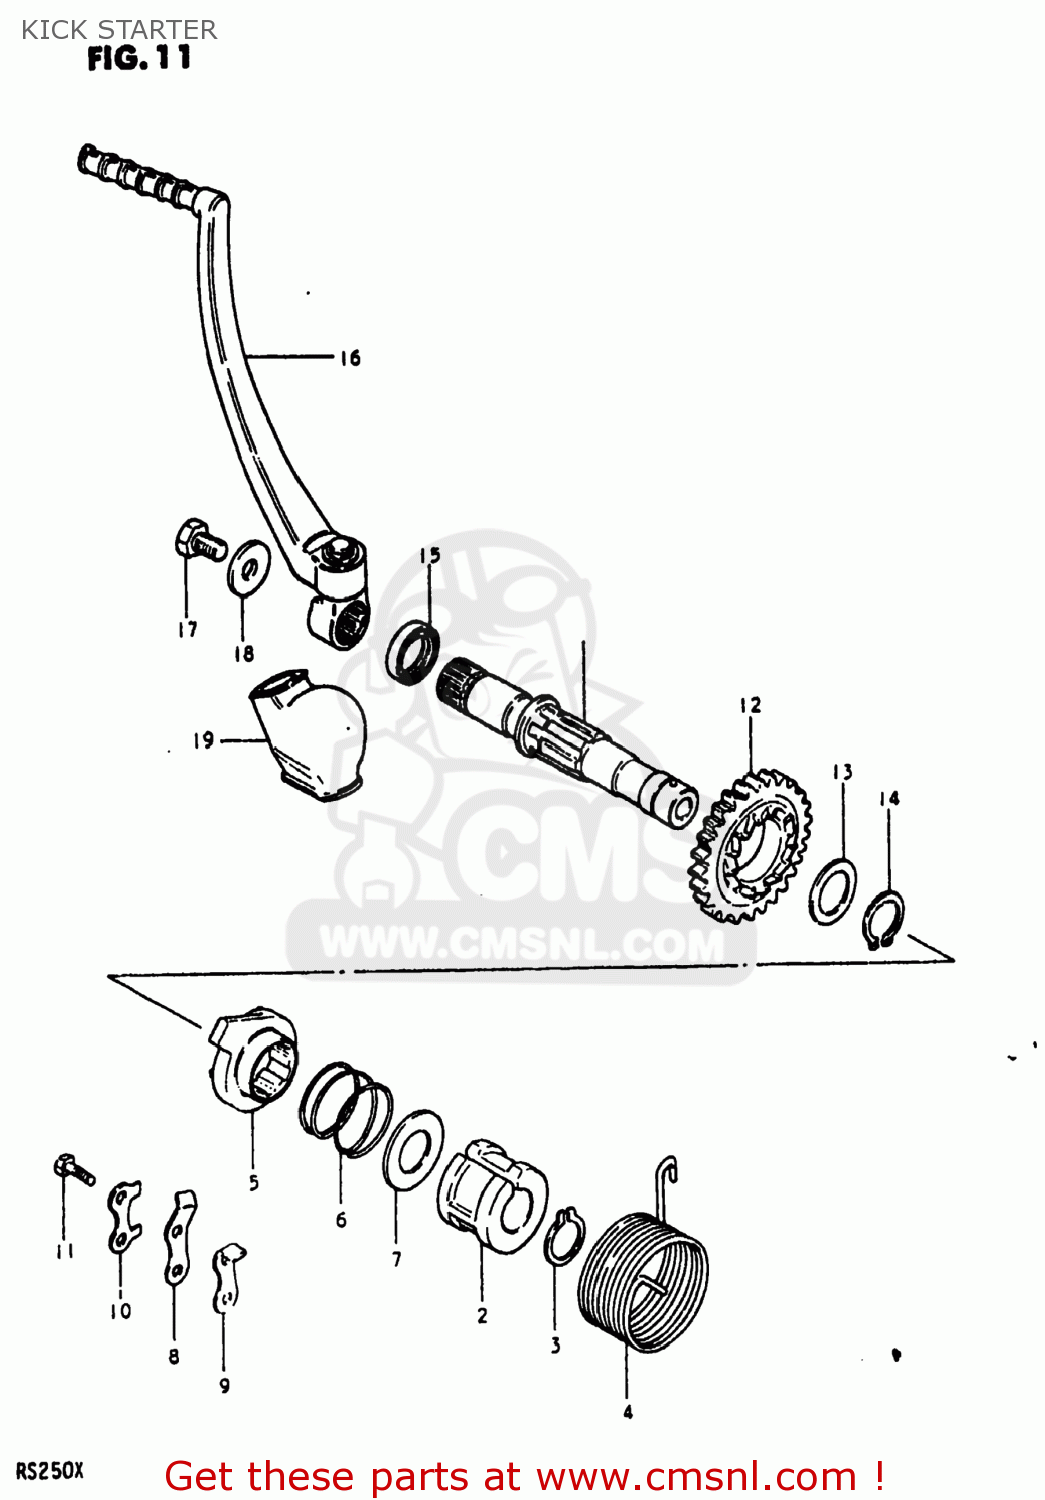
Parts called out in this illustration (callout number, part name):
1	SHAFT,KICK STARTER
2	GUIDE,KICK STARTER SFT SPRING
3	CIRCLIP
4	SPRING
5	STARTER,KICK
6	SPRING
7	WASHER
8	GUIDE,KICK STARTER
9	STOPPER,KICK STARTER
10	WASHER
11	BOLT
12	GEAR,KICK STARTER DRIVE
13	SHIM
14	CIRCLIP
15	SEAL,OIL(20X27X5)
16	LEVER ASSEMBLY,KICK STARTER
17	BOLT
18	WASHER(8.2X23X3.2)
19	COVER,KICK LEVER JOINT
